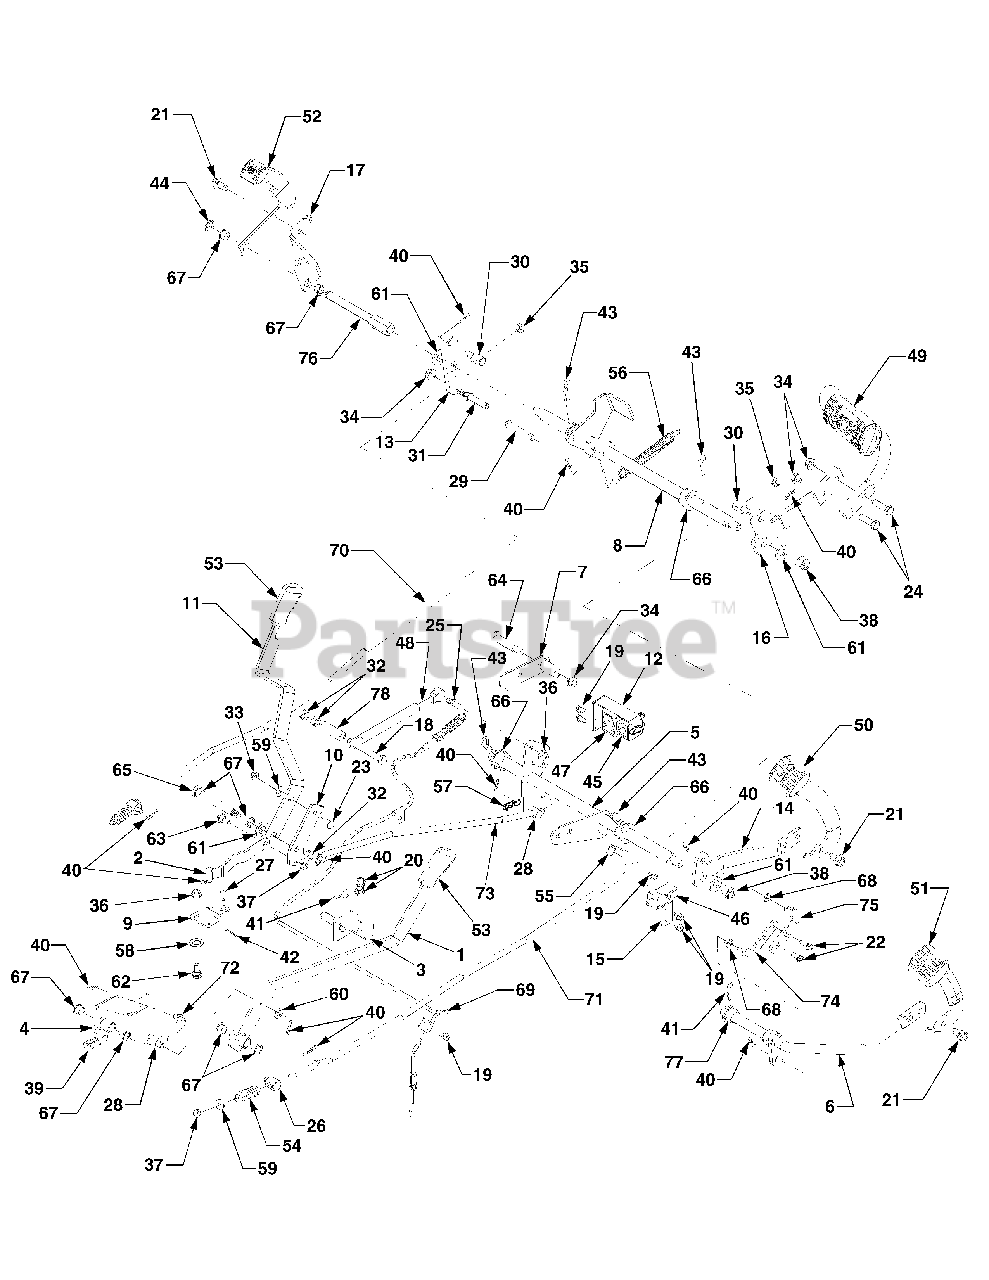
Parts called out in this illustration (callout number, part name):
1	Handle, 4WD
2	Link, Hi-Lo
3	Bracket, 4WD Pivot
5	Shaft Assembly, Pedal
6	Shaft Assembly, Reverse
7	Link Assembly, Parking Brake ..
8	Shaft Assembly, Brake
9	Link, Hi-Lo Pivot
17	Bracket, Pedal Brace
18	Screw, Hex Cap 3/8-16 x 3.0 GR8
19	Screw, Hex Wash Hd Tapp 1/4-20 x .5
20	Screw, Hex Wash. Hd. Tapp, 5/16-18 x .5
21	Screw, Hex Wash Hd Tapp 3/8-16 x .75
22	Screw, Hex Wash Hd Tapp 1/4-20 x .75
23	Screw.Carriage, 1/4-20 x .75 GR5
24	Screw, Hex Cap 3/8-16 x 1.25 GR5
25	Stud, Cylinder, 5/16-18
26	Ferrule, Brake
27	Pin, Clevis, .25 x .5
28	Ferrule, 3/8-24 x .37
29	Pin, Clevis, 3/8 x 2.015
30	Ferrule, 3/8 - 24 x .375
31	Pin, 3/8-16: 3/8 x 2.43
32	Nut, Hex Lock, 3/8-16
33	Nut, Hex Flange Nylon Lock 14-20 GRF
34	Nut, Hex Flange Lock, 3/8-16 ...
35	Nut, Hex Jam, 3/8-24
36	Nut, Hex Flange Lock, 5/16-18
37	Nut, Hex Flange Lock, 1/4-20 ...
38	Nut, Hex Insert Lock, 1/2-20
39	Link, Chain
40	Pin, Internal Cotter
41	Pin, Internal Cotter
42	Pin, Cotter, 3/32 x .750
43	Pin, Internal Cotter
44	E-Ring, .5 Dia
45	Switch, Plunger (Brake)
46	Switch, Plunger (Reverse)
47	Switch, Plunger (Brake)
48	Cylinder, Damper
49	Pedal, Brake
50	Pedal, Forward
51	Pedal, Reverse
52	Pedal, Diff. Lock
53	Grip, Handle
54	Spring, Compression
55	Spring, Rev/No Cut
56	Spring, Extension, .62 x 6.12
57	Spring, Extension, 3/8 x 1.44
58	Washer, Flat, .53 ID x .93 x .05 .
59	Washer, Flat, .28 x .74 x .063 ...
60	Washer, Flat, .375 x .74 x .063
61	Washer, Flat, .53 x .1.06 x .134
62	Screw, Shoulder, .435 x 1.78
63	Screw, Shoulder, ..375 x .181 ...
64	Screw, Shoulder, .498 x 1.635
65	Screw, Shoulder .498 x 3.245: 3/8-16
66	Bearing, Hex Flange, .752 ID
67	Bearing, Nylon. .50 ID x .341
68	Bearing, Flange, .375 x .58 x .25
69	Cable, Diff Lock
70	Rod, Brake, LH
71	Rod, Brake, RH
72	Link, 4WD Handle
73	Rod, Hydro Control
74	Rod, Rear Connecting
75	Rod, Front Connecting
76	Shaft, Diff. Lock
77	Bearing, Hex Flange, .629 ID
78	Spacer, .39 x .625 x 1.74
